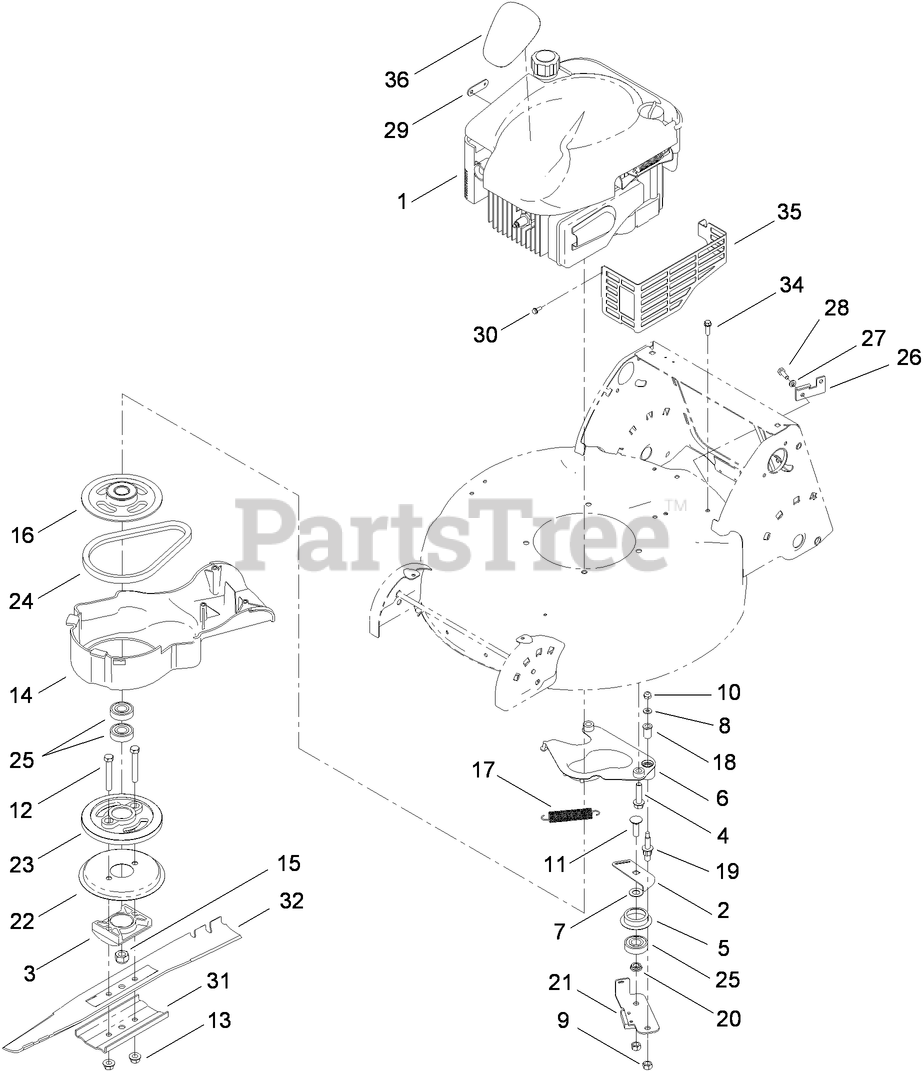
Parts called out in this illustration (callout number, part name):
2	PLATE-GUIDE
3	SUPPORT-BLADE
4	SCREW-HWH
5	RETAINER-BELT
6	PLATE-ANCHOR
7	SPACER
8	WASHER-FLAT
9	LOCKNUT
10	NUT-LOCK, NI
11	BOLT-CARR
12	SCREW-HH
13	NUT-LOCK
14	COVER-BBC
15	NUT-HEX
16	PULLEY
17	SPRING-TENSION, BRAKE
18	BUSHING
19	BOLT-SHOULDER
20	SPACER-BEARING
22	DISC
24	BELT
26	CLAMP-CABLE, BBC
27	WASHER-LOCK
28	SCREW-HH
29	PLATE-TERMINAL
30	SCREW-TAPTITE
31	SUPPORT-BLADE
34	SCREW-HWH
35	SHIELD-MUFFLER
36	DECAL-ENGINE
